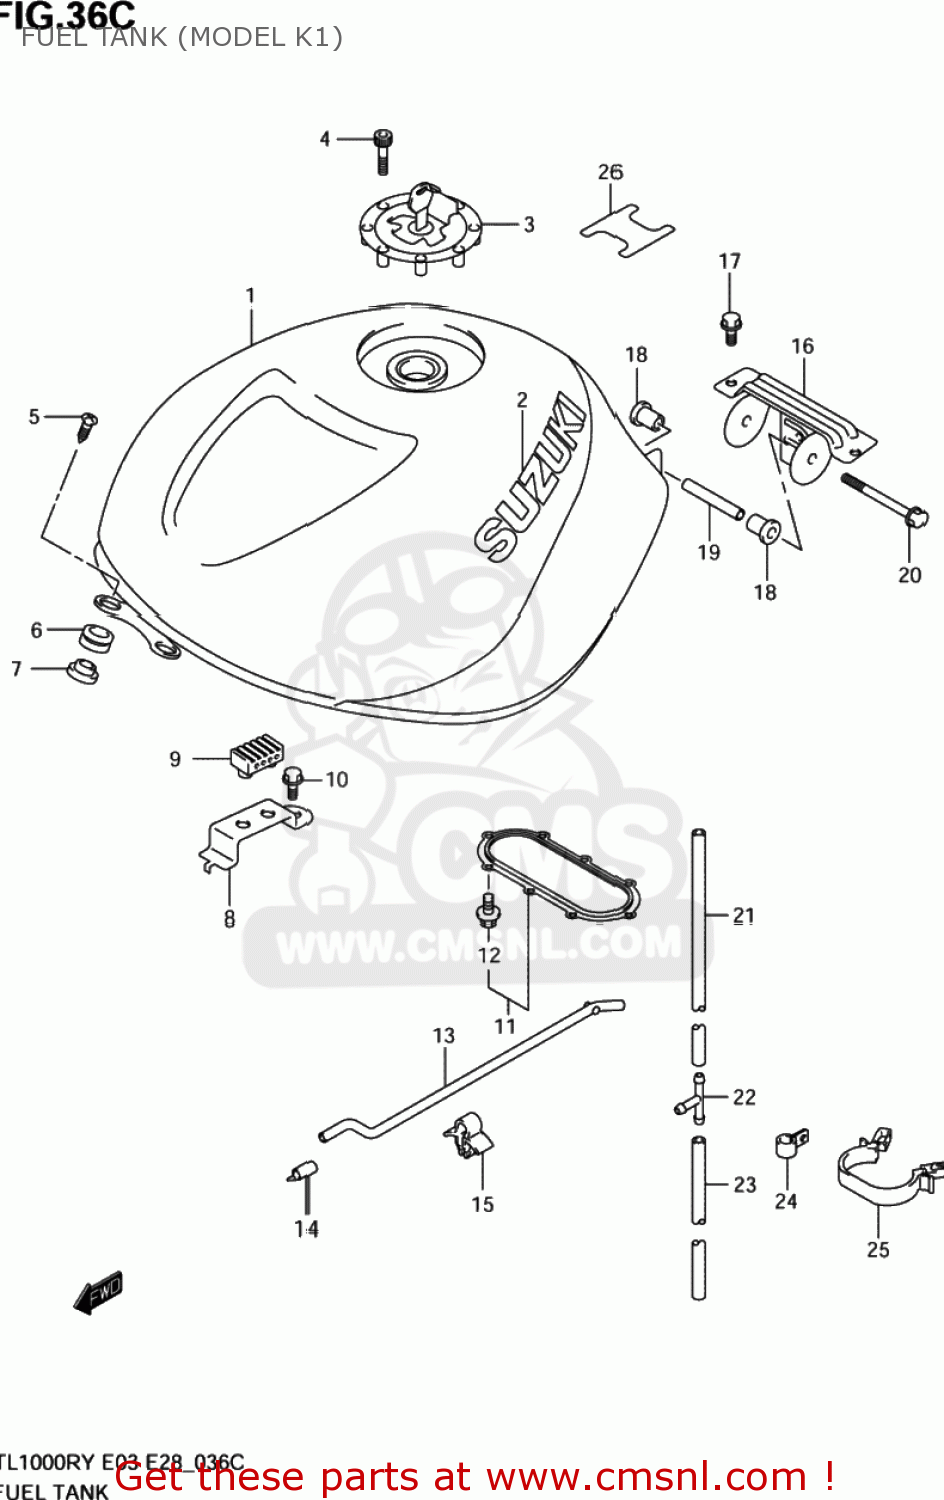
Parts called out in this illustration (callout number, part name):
1	TANK ASSY,FUEL
2	EMBLEM,FUEL TANK
3	CAP SET,FUEL TANK
4	BOLT(5X20)
5	SCREW(6X25)
6	CUSHION
7	WASHER
8	BRACKET,FUEL TANK SIDE CUSHION
9	CUSHION,SEAT(40X20X15)
10	BOLT
11	PACKING SET,FUEL PUMP (NAS)
12	BOLT,FUEL PUMP
13	STAY,FUEL TANK
14	CAP,OD:11
15	CLAMP
16	BRACKET,FUEL TANK RR
17	BOLT
18	CUSHION,FUEL TANK RR
19	SPACER,FUEL TANK RR
20	BOLT
21	HOSE,FUEL TANK DRAIN
22	3 WAY
23	HOSE(7X10.2X600)
24	CLAMP
25	CLAMP
